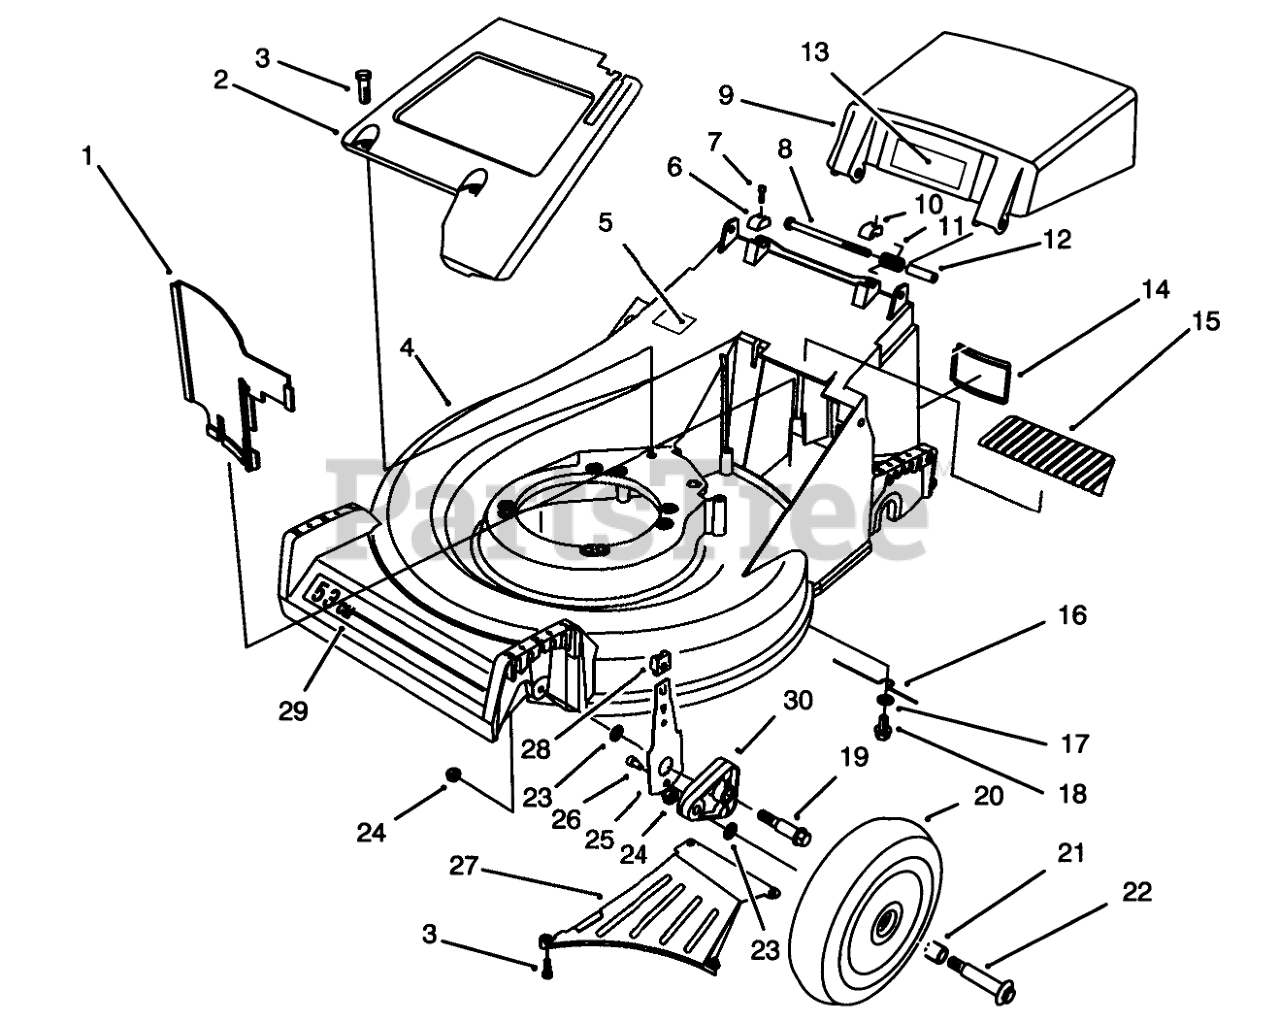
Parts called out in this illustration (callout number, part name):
1	PANEL-VERTICAL
2	PaneI-Screen
3	SCREW-HWHTF
4	Housing-53cm (Incl. Ref. #5 & 29)
5	Decal-Noise
6	CAP-HINGE BOLT, RH
7	SCREW-HSH
8	SCREW-HH
9	Door Discharge
10	CAP-HINGE BOLT, LH
11	SPRING-DOOR
12	SPACER-DOOR
13	DECAL-DANGER
14	COVER-ACCESS
15	COVER-TOP
16	RETAINER-BELT
17	WASHER-FLAT
18	SCREW-HHFTF
19	BOLT-SHOULDER
20	Wheel & Tire Assembly (Incl. Ref. #21)
21	BUSHING
22	WHEEL BOLT
23	WASHER
24	NUT-LOCK
25	FRONT SPRING ARM ASM
26	SCREW-HSH, THREAD FORMING
27	Ramp-Discharge
28	KNOB-ARM
29	DECAL
30	ARM-PIVOT, FRONT
